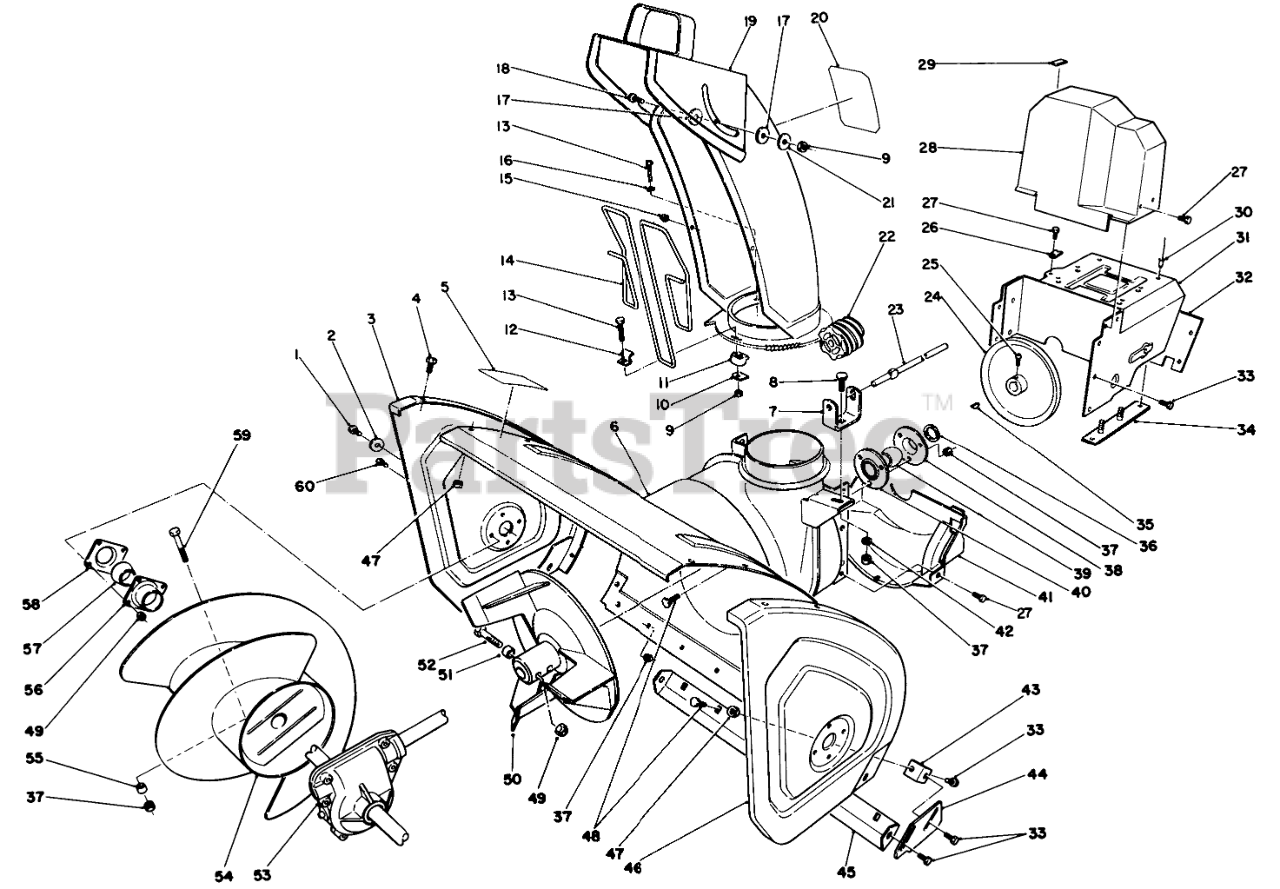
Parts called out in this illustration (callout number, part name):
1	SCREW-HH
2	WASHER
3	PLATE-SIDE, RH
4	SCREW-HHF
5	DECAL-WARNING, AUGER
6	Housing-24"
7	BRACKET-WORM, CHUTE
8	BOLT-CARR
9	NUT-LOCK, NI
10	PLATE-RETAINER, CHUTE
11	RETAINER-CHUTE
12	CLIP-GUARD, CHUTE
13	SCREW-HSH
14	GUARD-CHUTE
15	NUT-PUSH
16	WASHER-FLAT
17	WASHER-PLASTIC
19	Assembly
20	DECAL-DANGER DISCH.
21	WASHER-FLAT
22	GEAR-WORM
23	ROD-CHUTE, LOWER
24	PULLEY-IMPELLER
25	SCREW-SET, SQH
26	RETAINER-CABLE
27	SCREW-HWH
28	COVER-BELT, UPPER
29	COVER-CABLE
30	RIVET-POP
31	Frame-Engine
32	Cover-Frame, Engine
33	SCREW-HHF
34	LH FRAME PLATE ASM
35	KEY-WOODRUFF
36	WASHER-THRUST
38	NUT-LOCK, NI
39	Bearing-Impeller
40	BEARING-BALL
41	Cover-Belt (Lower)
42	WASHER-PLAIN
43	Bracket-Skid
44	Plate-Skid LH
45	Blade-Scraper
46	Plate-Side LH
47	NUT-LOCK, NI
48	SCREW-CARR
49	NUT-LOCK, NI
50	Impeller
51	SPACER
52	SCREW-HHF
53	Auger Gearbox Assembly
54	Auger-R.H.
55	SPACER-HUB, AUGER
56	BEARING-FLANGE, FRONT
57	BEARING
58	BEARING-FLANGE, REAR
59	Auger Bolt
60	SCREW-HH
